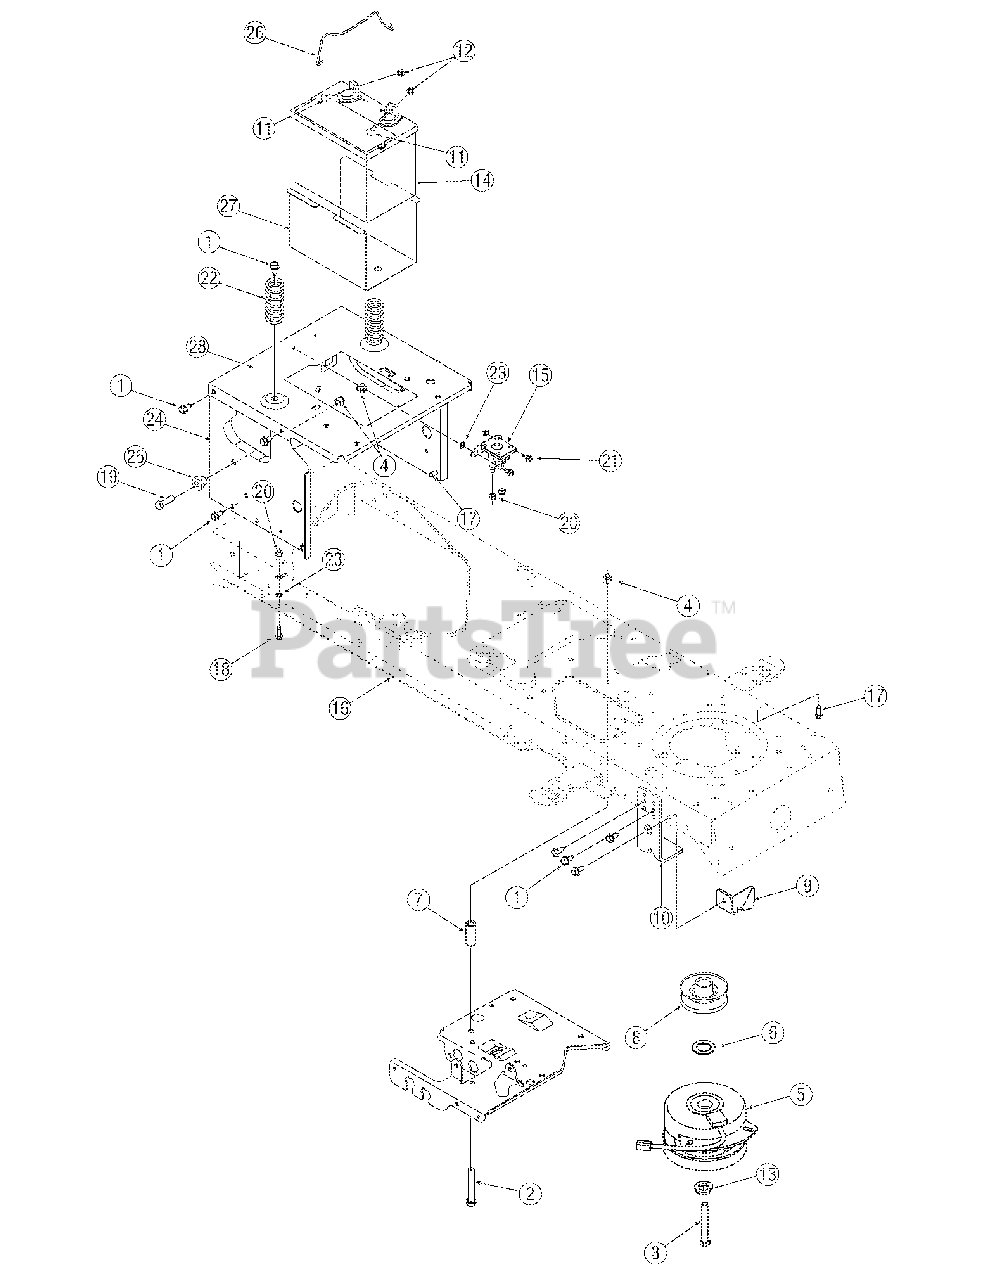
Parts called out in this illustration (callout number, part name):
1	Screw, 5/16-12, 0.75
2	Screw, 3/8-16, 2.50, Gr5
3	Screw, 7/16-20, 3.50, Gr5, Lock
4	Nut, Flange Lock, 3/8-16, GrF
5	PTO Clutch, Electric
6	Washer, Flat, 1.031 x 1.620 x .095
7	Spacer,.385 ID x.635 OD x 1.54
8	Pulley, Engine, 3.56 Diameter
11	Screw, Carriage, 1/4-20,.75, Gr5
12	Nut, Sems, 1/4-20
13	Lock Washer, 7/16
14	Battery, 235 CCA
15	Solenoid, 12V, 100 Amp
18	Screw, 1/4-20, 0.750
19	Screw, 3/8-16, 1.25, Gr5
20	Nut, Flange Lock, 1/4-20,
21	Screw, 1/4-20, 0.50
22	Spring, Compr., 1.28 OD x 3.125
23	Washer, Lock, 1/4, External
26	Hold Rod, Battery
